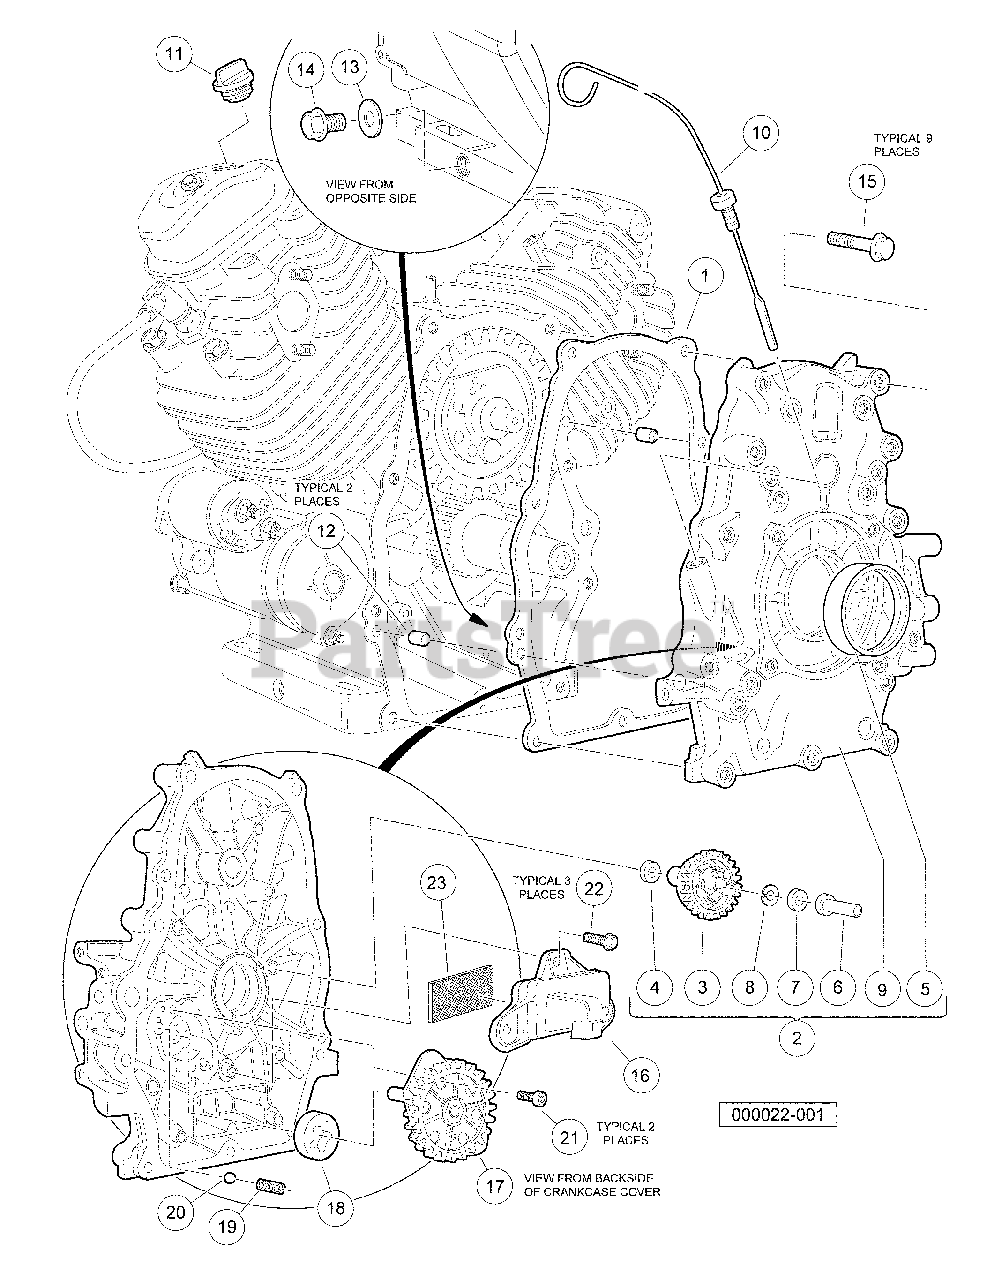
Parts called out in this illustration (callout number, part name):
1	Gasket, Case Cover
2	Cover Assembly, Crankcase
3	Governor Assembly
4	Washer, Plain, M6
5	Seal, Oil, 38 X 58 X 9
6	Slider, Governor
7	Washer, 6 X 16
8	Clip, Governor
9	Cover, Crankcase
10	Dipstick, Oil
11	Cap, Oil Filler
12	Pin A, Dowel, 8 X 14
13	Washer, Drain Plug, M14
14	Bolt, Drain Plug , M14
15	Bolt, Flange Head, M8 X 1.25 X 50
16	Cover, Oil Filter
17	Cover Assembly, Oil Pump
18	Rotor, Oil Pump, Outer
19	Spring, Relief Valve
20	Ball, Steel , 3/8, #12
21	Bolt, Socket
22	Bolt, Flange Head, M6 X 1 X 20
23	Screen, Oil Filter
